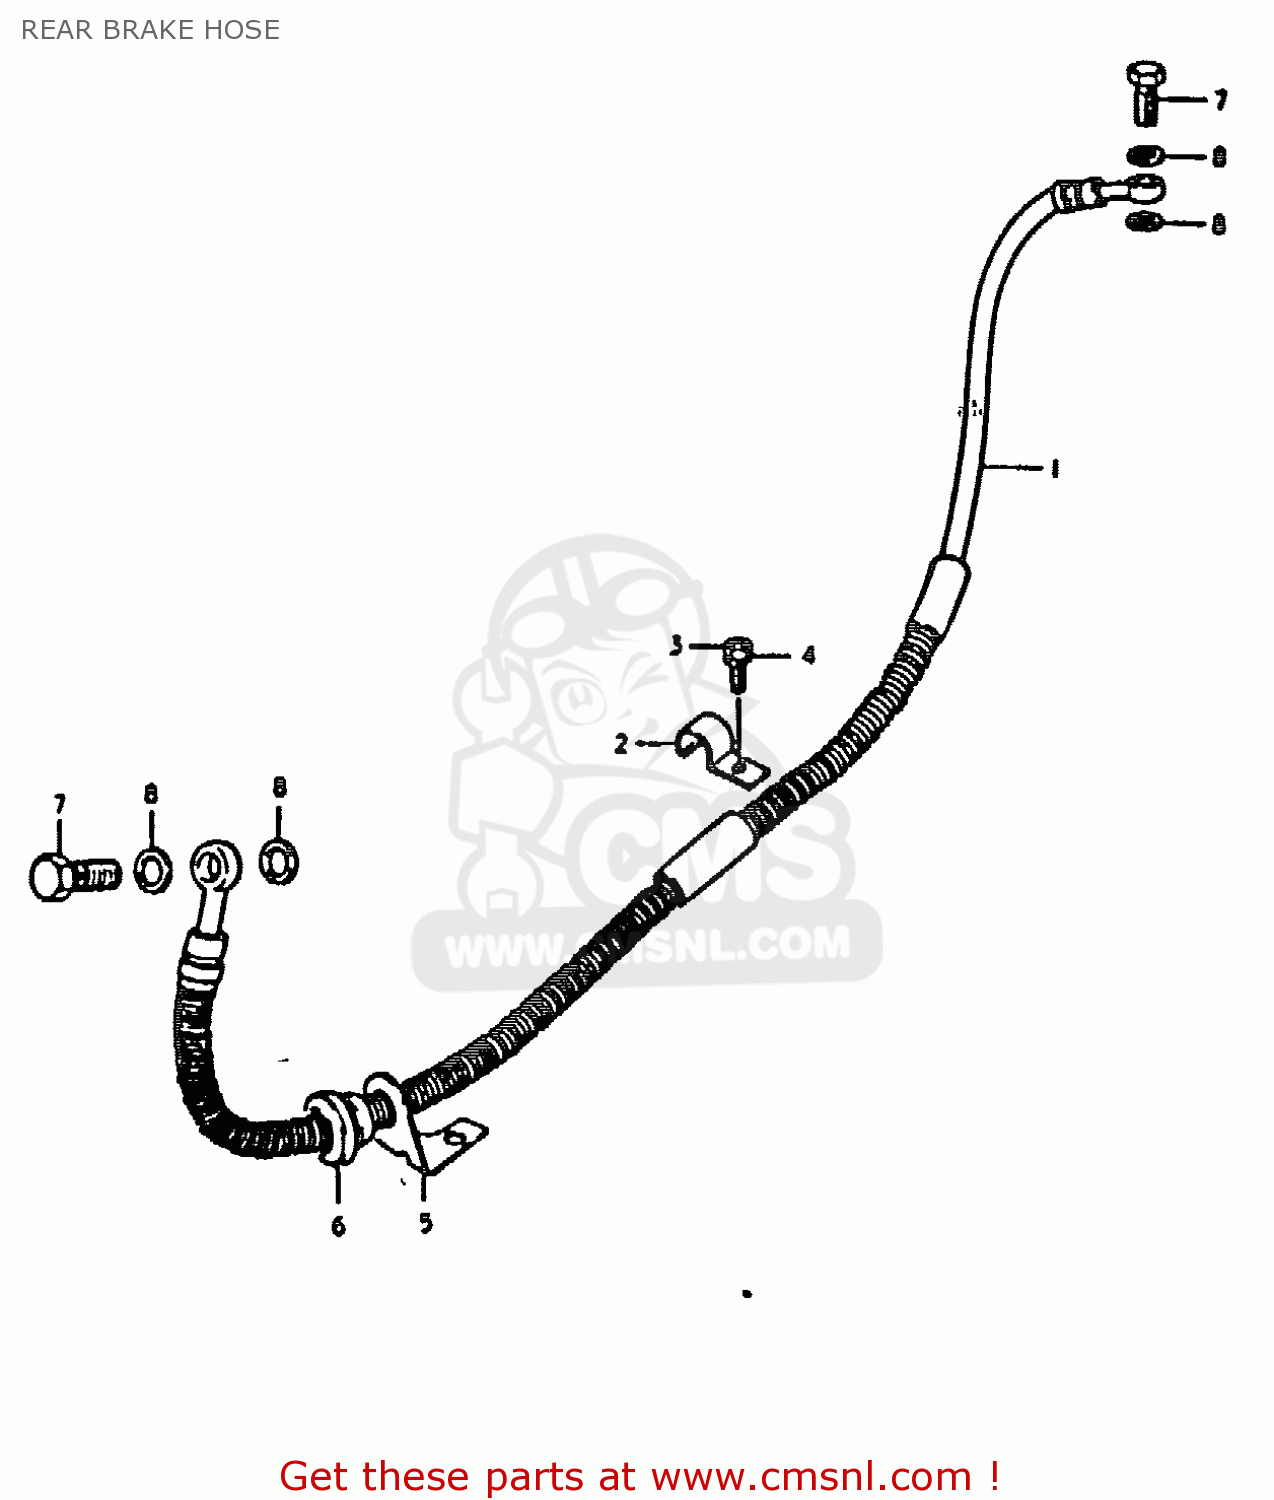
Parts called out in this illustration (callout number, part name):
1	HOSE,REAR BRAKE
2	CLAMP,REAR BRAKE HOSE
3	SCREW(6X8)
4	LOCK WASHER
5	GUIDE,BRAKE HOSE
6	GROMMET,BRAKE HOSE GUIDE
7	BOLT UNION
8	WASHER
